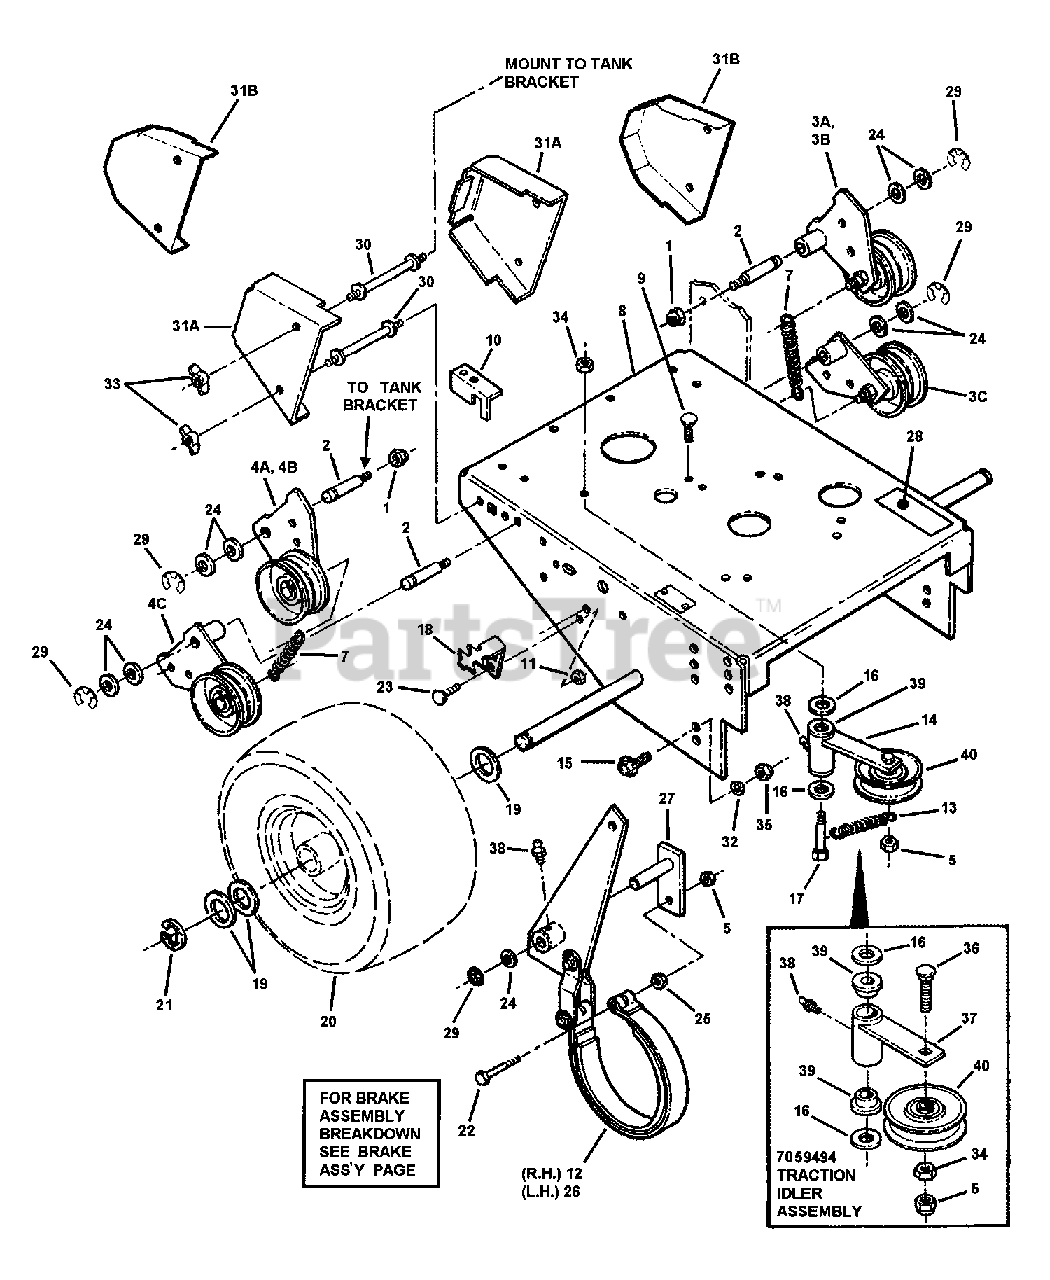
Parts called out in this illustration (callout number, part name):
1	NUT, 3/8-24 Hex Nyloc
2	STUD, Shoulder
3A	IDLER ASSY, Upper Left (see Footnote 1)
3B	IDLER ASSY, Upper Left
3C	IDLER ASSY, Lower Left
4A	IDLER ASSY, Upper Right
4B	IDLER ASSY, Upper Right
4C	IDLER ASSY, Lower Right
5	NUT, 3/8-16 HEX NYLON LOCK
7	SPRING, Extension
8	FRAME, Engine (Weldment)
9	BOLT, 3/8-16 x 1" Square Neck Carriage, GR 5
10	BRACKET, Anti-Spin
11	NUT, 5/16-18 HEX NYLON LOCK
12	ASSEMBLY, Brake Band, RH
12	ASSEMBLY, Brake Band, 6" Thomas
13	SPRING, Extension
14	ASSEMBLY, Idler Arm
15	BOLT, 1/2-13 x 1-1/4" Hex Flange Lock, GR 5
16	WASHER, 9/16" Flat (Narrow Type)
17	SHOULDER BOLT, 3/8-16 x 2-7/16"
18	SCRAPER, Wheel Pulley
19	BUSHING, 1" x 14 Ga Machine
20	ASSEMBLY, Wheel/Drum/Pulley
21	E RING, Retaining
22	BOLT, 3/8-16 X 2, GD5, CZ
23	BOLT, 5/16-18 x 1" Short Neck Carriage, GR 5
24	BUSHING, Machine, 5/8"
25	NUT, 3/8-16 Hex, GR 5 or B
26	ASSEMBLY, Brake Band, LH
27	WELDMENT, Brake Stud
28	DECAL, Caution
29	RING, 5/8" External Retaining
30	STUD, Fender Mount (3/8-16 thread, both ends)
31A	BELT COVER, Express
31B	BELT COVER, Express
32	WASHER, 1/2" Split Lock
33	WINGNUT, 3/8-16 w/Nylon Ring
34	NUT, 3/8-16 Hex Center Lock
35	NUT, 1/2-13 HEX
36	BOLT, 3/8-16 x 2" Short Neck Carriage, GR 5
37	WELDMENT, Idler Arm, Express
38	LUBE FITTING, 3/16 Press-In
39	FLANGE BEARING, 9/16 I.D.
40	IDLER, V-Belt, 3.56 O.D.
